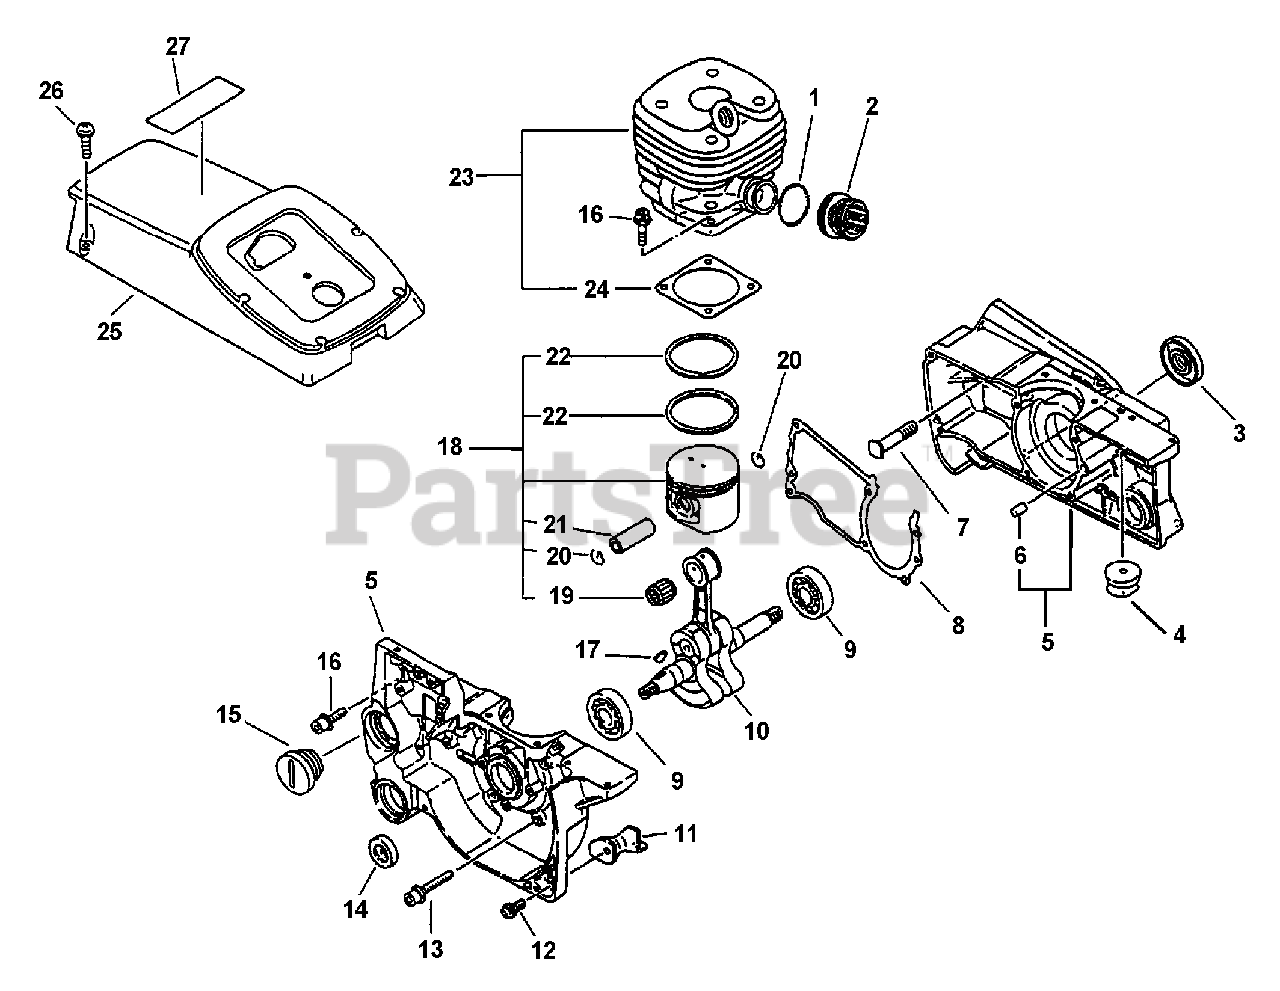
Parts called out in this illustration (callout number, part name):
2	BELLOWS, INTAKE
3	SEAL, OIL
4	CUSHION - A
5	CRANKCASE KIT
6	PIN - LOCATING
7	STUD, GUIDE BAR
8	GASKET, CRANKCASE
9	BEARING, BALL - 6202
10	CRANKSHAFT ASSY
12	SCREW - 5X14
13	SCREW - 5X35
14	SEAL, OIL
15	CAP, OIL TANK
16	SCREW - 5X20
18	PISTON KIT
19	BEARING, NEEDLE
20	RING, RETAINING
21	PIN, PISTON
22	RING, PISTON
23	CYLINDER KIT
24	GASKET, CYLINDER
25	COVER, ENGINE
26	SCREW - 5X20
27	LABEL - CAUTION
